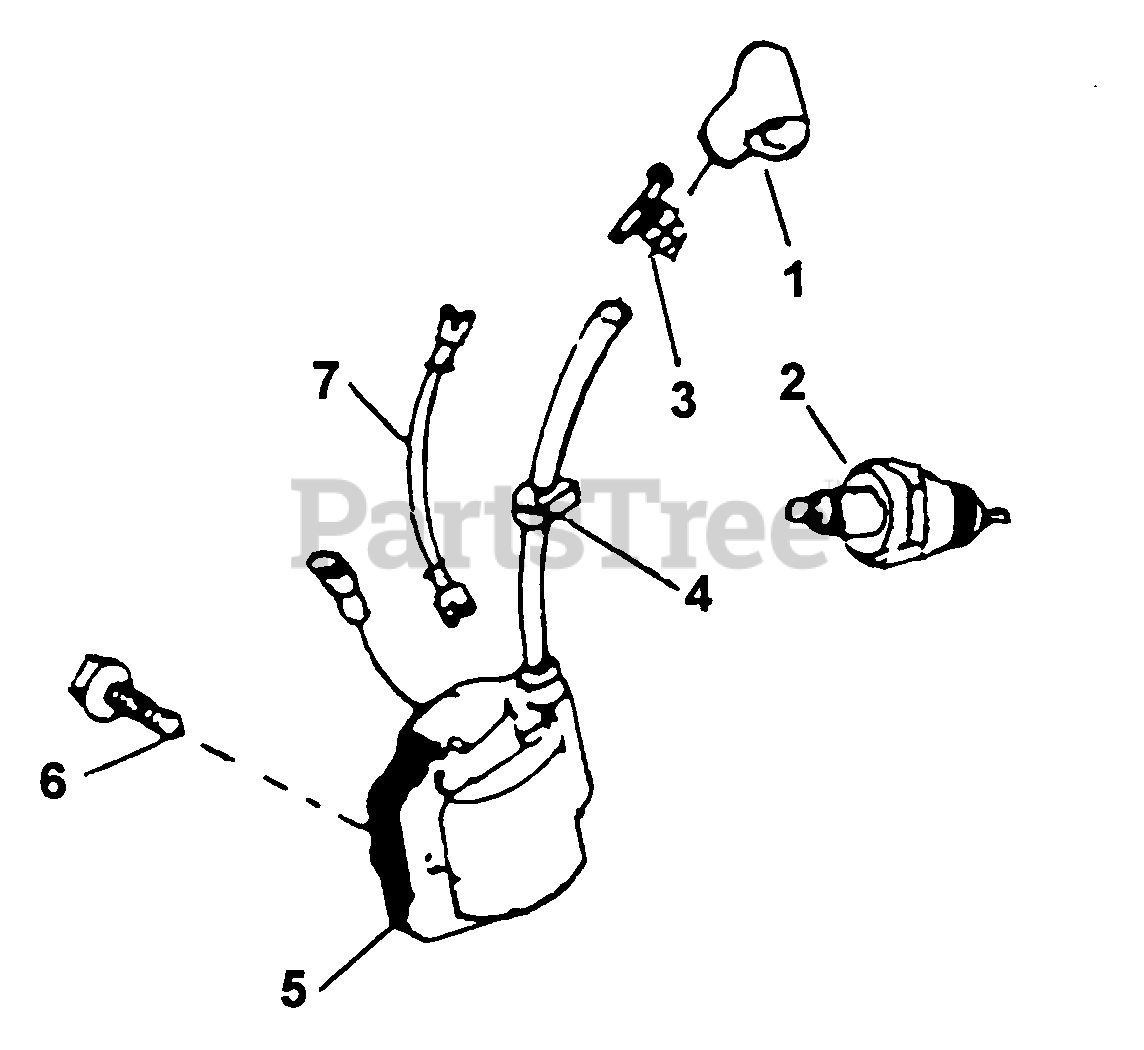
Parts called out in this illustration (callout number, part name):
2	SPARK PLUG
3	CONNECTOR
5	COIL, IGNITION
7	WIRE, GROUND
